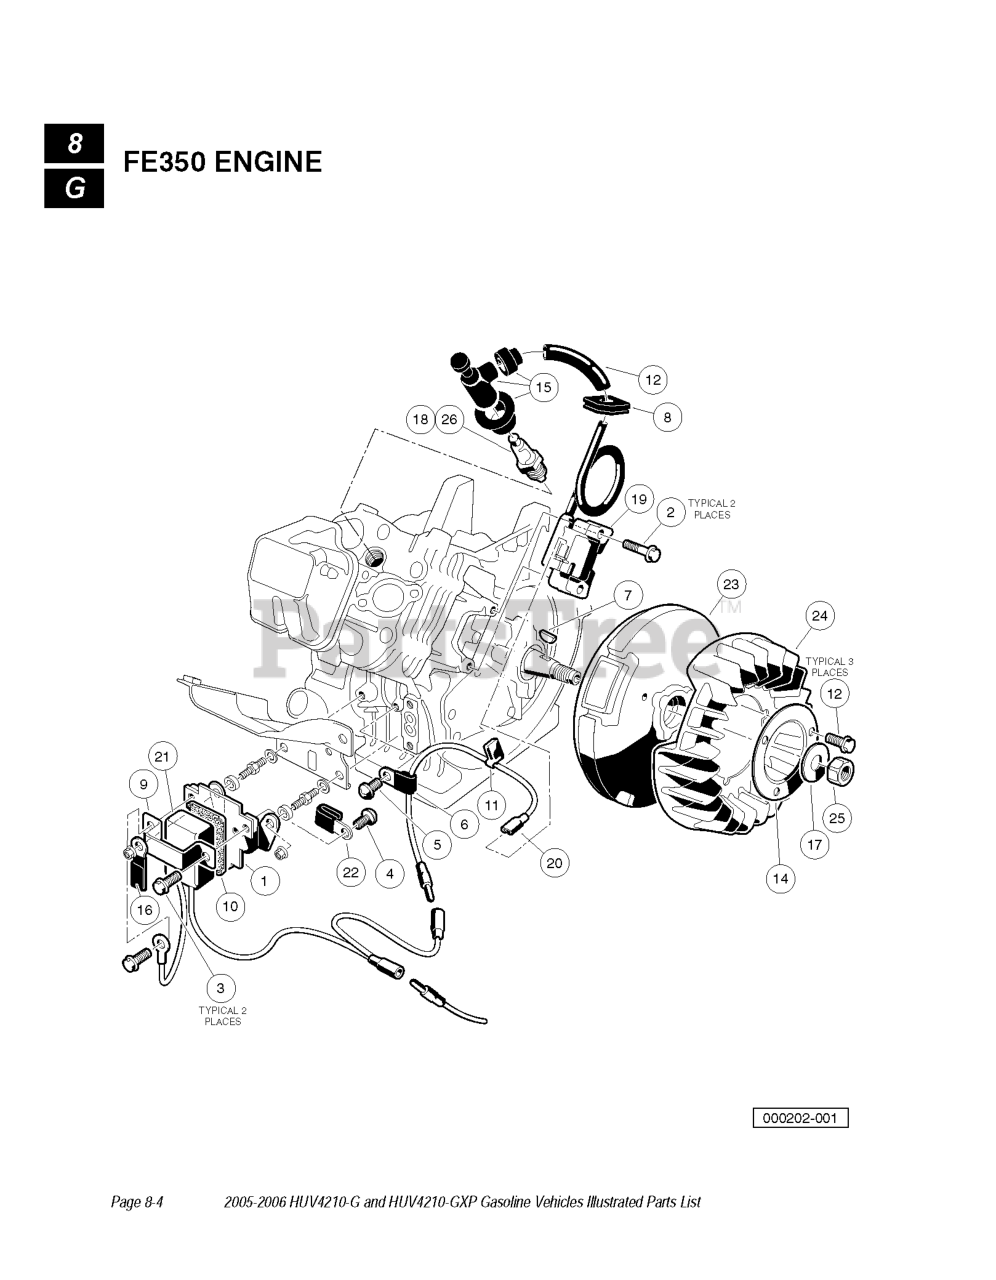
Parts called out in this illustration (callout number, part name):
1	BRACKET, RPM LIMITER
2	BOLT, FLANGED
3	BOLT, FLANGED
4	SCREW, PAN WP CROSS
9	BAND, RPM LIMITER MOUNT
10	DAMPER, RPM LIMITER
12	TUBE, 7MM X 10MM X 70MM
13	BOLT - FLANGED
15	CAP ASM PLUG
17	WASHER, FLAT
18	SPARK PLUG OHV
19	COIL, IGNITION
20	LEAD WIRE ASSY
21	LIMITER, RPM
23	FLYWHEEL COMPLETE, FE350
24	FAN, FE350 CW
25	Flywheel, Complete
26	NGK OHV SPARK PLUG
